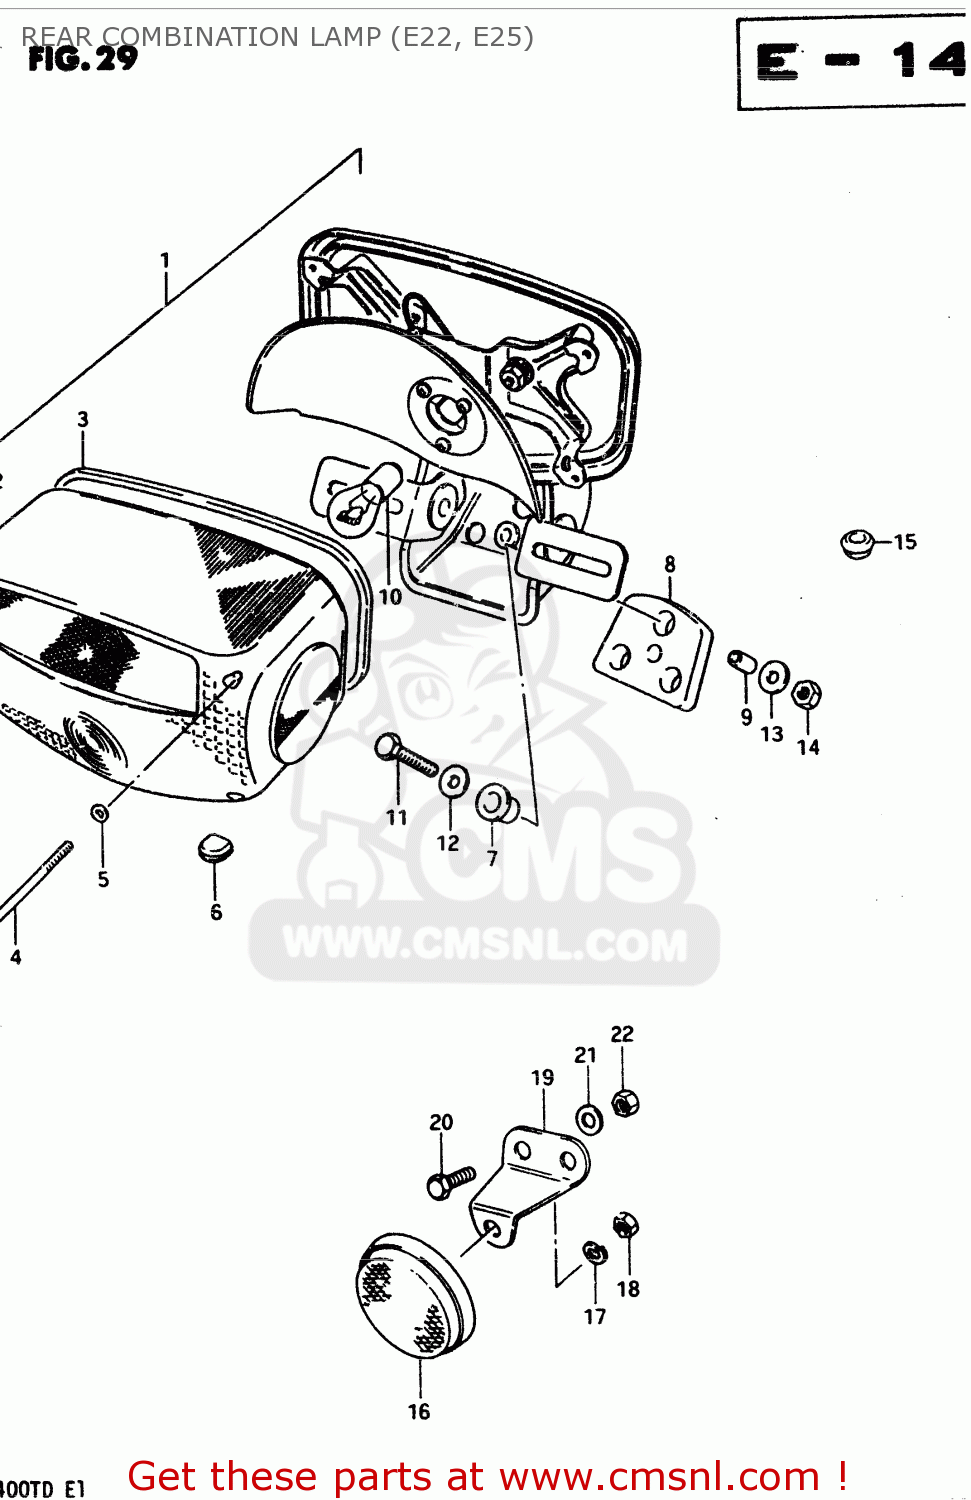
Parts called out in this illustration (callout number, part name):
1	LAMP ASSY,RR C
2	LENS,RR COMBIN
3	GASKET (NAS)
4	SCREW (4X55)
5	GASKET (NAS)
6	GROMMET
7	CUSHION
8	CUSHION
9	SPACER
10	BULB(12V21/5W)
11	BOLT
12	WASHER (6.5X20X1.2)
13	WASHER
14	NUT
15	GROMMET
16	REFLEX REFLECTOR,RR
17	LOCK WASHER
18	NUT
19	BRACKET
20	BOLT
21	WASHER
22	NUT
